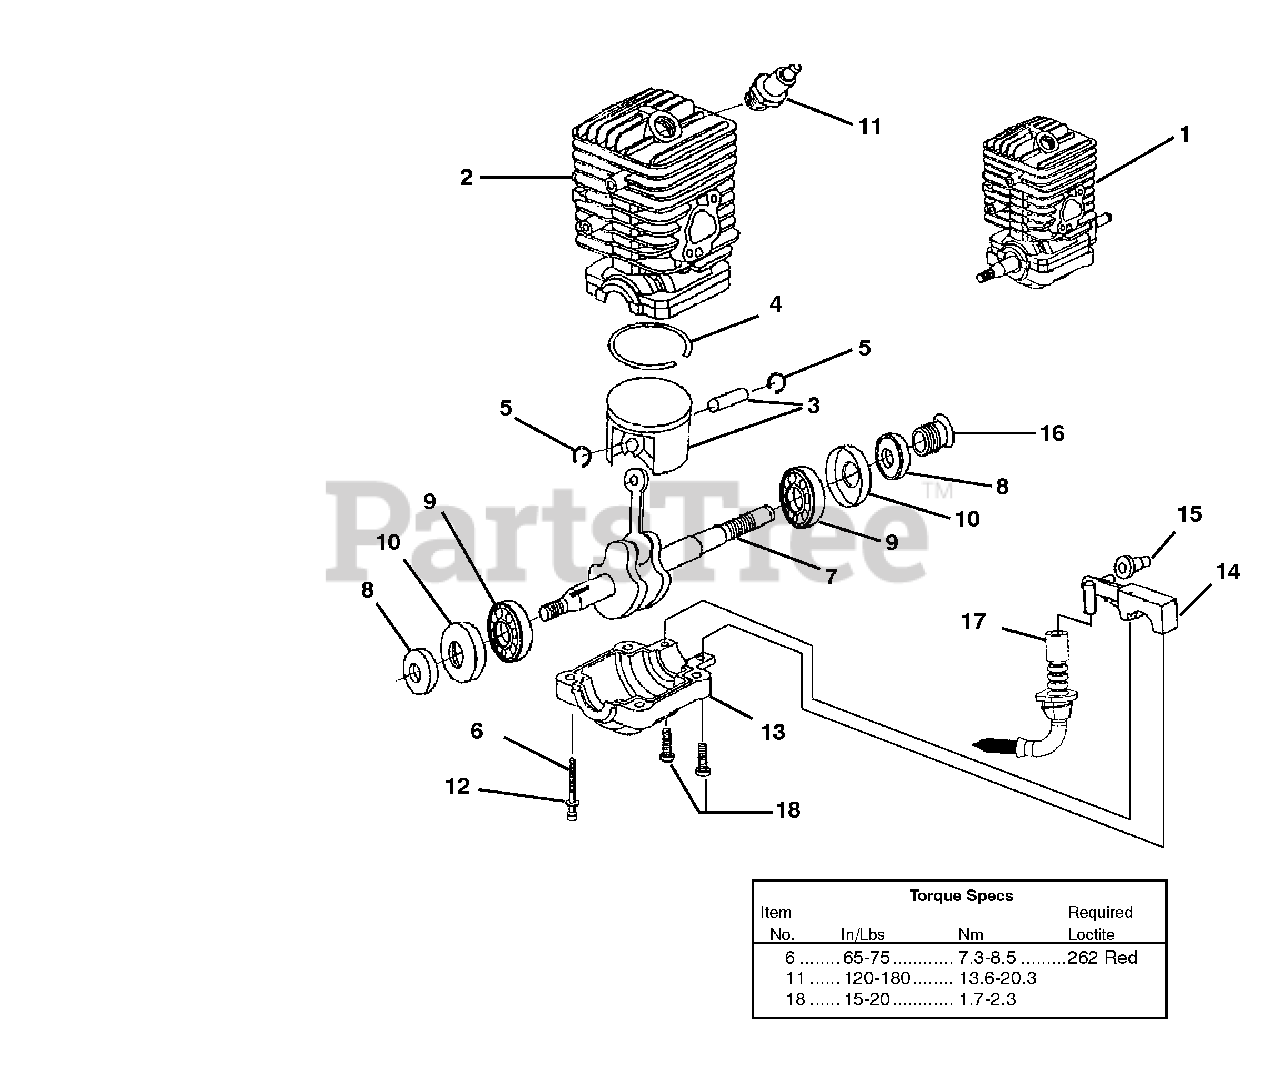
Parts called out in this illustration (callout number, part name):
1	Short Block, Complete (45cc)
2	Cylinder Kit (45cc)
3	Piston & Pin (45cc)
4	Piston Ring (45cc)
5	Ring, Retaining
6	Screw, Cap-Socket Hd. (10-24 x 2")
7	Crankshaft & Rod Assy (45cc)
8	Shaft Seal
9	Ball Bearing
10	Rubber Case
11	Spark Plug
12	Washer
13	Lower Crankcase (45cc)
14	Oil Pump Kit
15	Grommet, Oil Outlet
16	Left Hand Worm
17	Oil Intake Tube w/Filter
18	Screw, T.F. (8-16 x 5/8")
